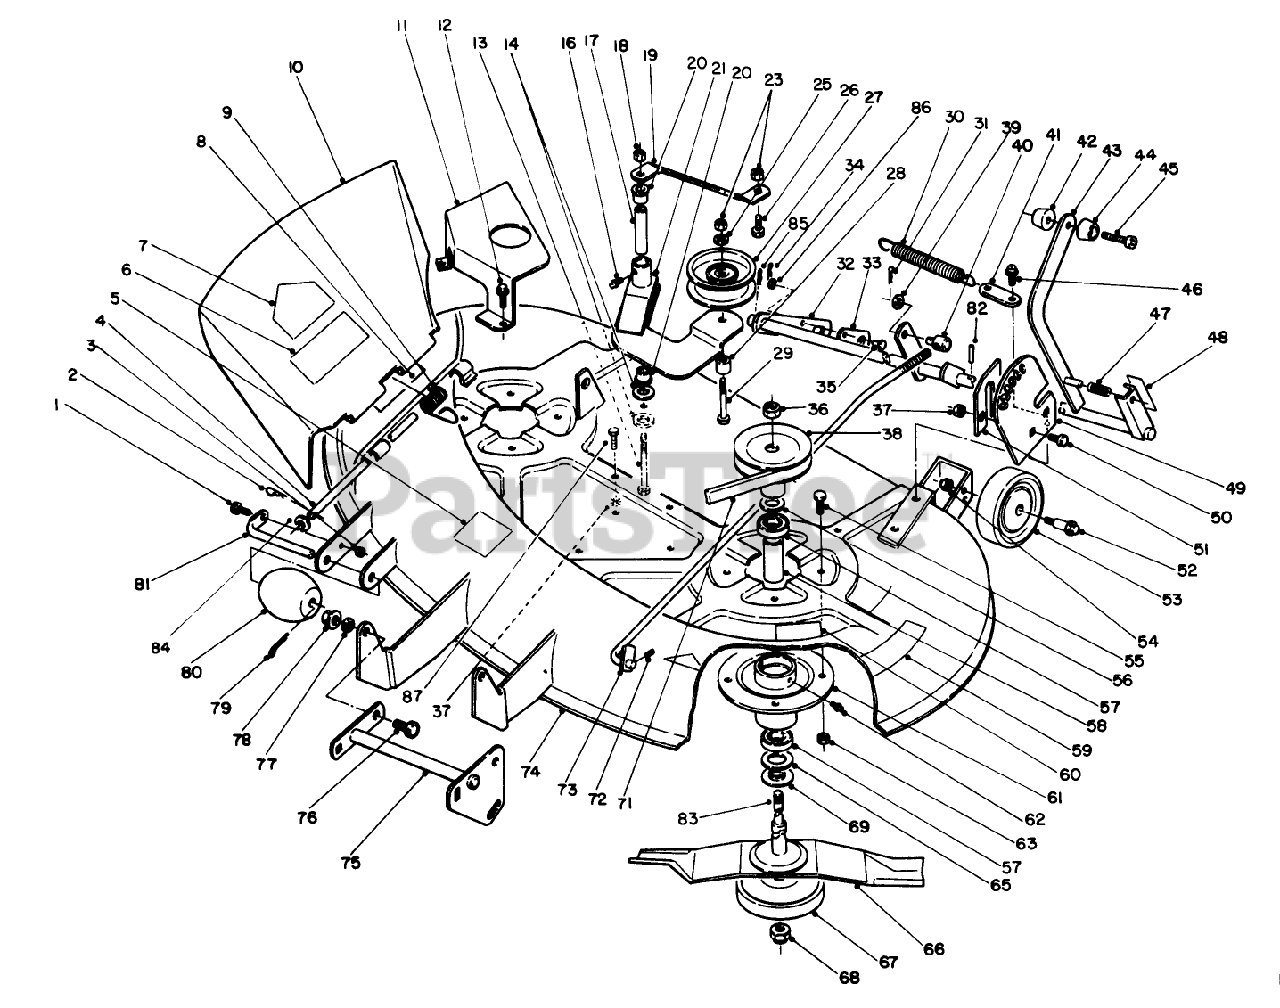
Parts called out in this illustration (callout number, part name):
1	SCREW-HH
2	PIN-COTTER
3	NUT-LOCK, NI
5	Decal-Routing
6	DECAL-DANGER, THROWN OBJECT
7	DECAL-DANGER
8	DECAL-DANGER
9	SPRING-TORSION
10	Deflector
11	COVER-BELT R
12	SCREW-HWHTF
13	SCREW-HH
14	WASHER
16	FITTING-GREASE
17	SPACER
18	NUT-LOCK, NI
19	BRACE R
20	BUSHING
21	WLDMT-IDLER ARM R
23	NUT-LOCK, NI
25	WASHER-FLAT
26	BOLT-CARR
27	PULLEY-IDLER
28	SPACER
29	SCREW-HH
30	SPRING-EXTENSION
31	Hairpin Cotter
32	WLDMT-HEIGHT ADJ R
33	LATCH B
34	PIN-COTTER
35	Pin-Clevis
36	NUT-LOCK NI
37	NUT-LOCK, NI
38	PULLEY-SPINDLE
39	WASHER-FLAT
40	STUD-TRUNION
41	Lever
42	KNOB
43	WLDMT-LIFT LEVER R
44	KNOB
45	BOLT-4
46	Bolt
47	SPRING-COMPRESSION
48	DECAL-HOC
49	QUADRANT R
50	BOLT-CARR
51	PLATE-RETAINING R
52	BOLT-WHEEL
53	WHEEL-DECK
54	NUT-LOCK, NI
55	SCREW-HH
56	Washer
57	BEARING-BALL
58	BEARING SPACER
59	DECAL - DANGER
60	DECAL-OVERLAY
61	Housing-Spindle
62	ZERK FITTING
63	NUT-LOCK, NI
65	RING-RETAINING
66	Blade
67	Cup
68	NUT-LOCK NI
69	SPACER-SPINDLE
71	BELT-V
72	PIN-SPRING
73	WLDMT-HEIGHT ADJ R
74	Deck-Mower
75	ASM-FRONT LIFT R
76	SCREW-CARR
77	SPACER
78	LOCKNUT-FLANGE
79	PIN-COTTER
80	ROLLER
81	SHAFT-ROLLER
82	PIN-SPIROL
83	W.A.-SPINDLE SHAFT
84	WASHER-PLAIN
85	PIN-COTTER
86	Washer
87	SCREW-HH
